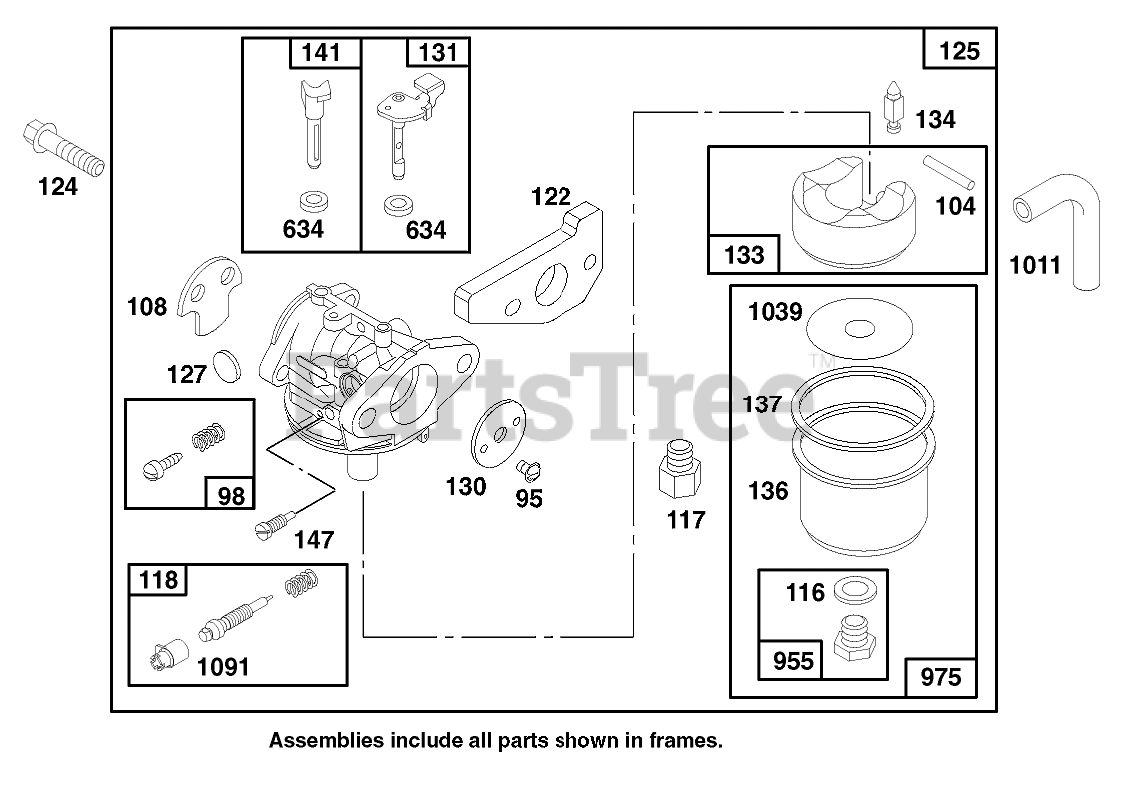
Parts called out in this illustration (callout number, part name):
95	SCREW - ROUND HEAD
98	IDLE ADJUSTING SCREW
104	FLOAT HINGE PIN
108	CHOKE VALVE
116	SEALING GASKET
117	Jet-Main
118	VALVE KIT - NEEDLE
122	ADAPTER ASSEMBLY
124	HEX HEAD SCREW
125	CARBURETOR ASSEMBLY
127	PLUG
130	THROTTLE VALVE
131	THROTTLE SHAFT
133	FLOAT-CARBURETOR
134	Valve-Inlet (Includes Seat)
136	FLOAT BOWL
137	FLOAT BOWL GASKET
141	CHOKE SHAFT
147	JET ADAPTER
634	SEAL WASHER
955	HEX HEAD SCREW
975	CARBURETOR BOWL ASM
1011	VENT TUBE
1039	FLOAT LIMITER
1091	CAP - LIMITER
